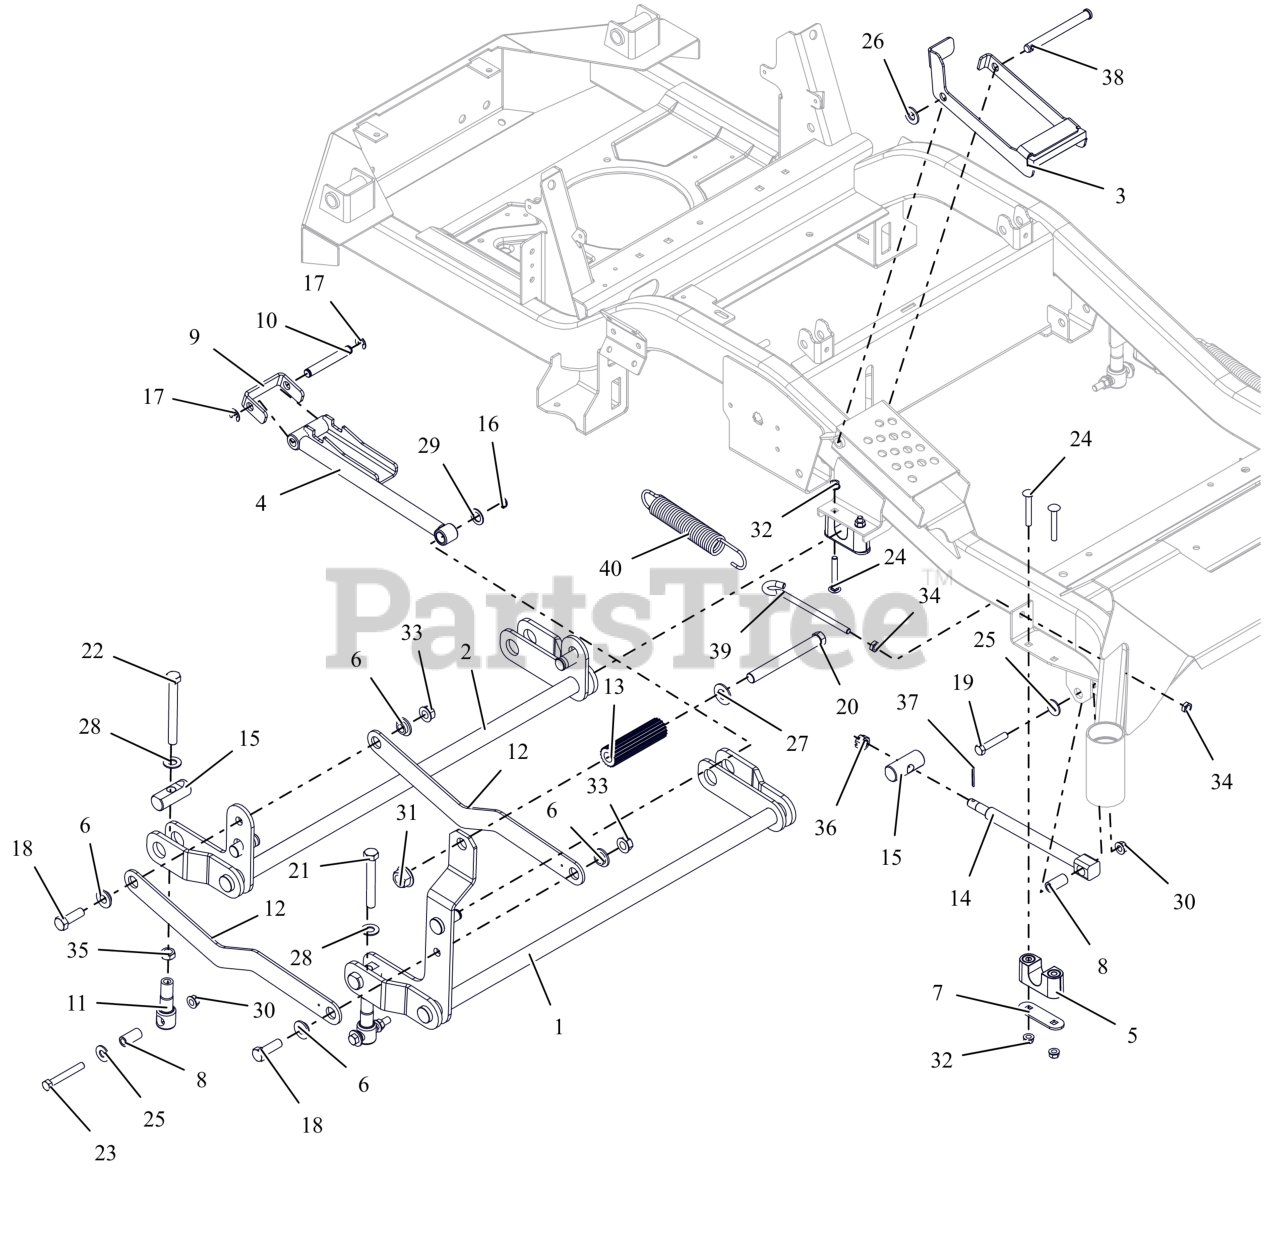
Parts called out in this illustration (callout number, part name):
1	WLDMT, FRONT DECK LIFT PIVOT
2	WLDMT, REAR DECK LIFT PIVOT
3	BRKT, HOC TRANSFER LOCK
4	WLDMT, HOC ARM
5	ASM-BUSHING, DECK LIFT
6	BSHG-FLG .515X.750X.395X1.120
7	PLATE, BEARING SUPPORT
8	SPACER, DECK LEVELING
9	BRKT, HOC LINE
10	ROD, HOC PIVOT
11	LINK, DECK LIFT FORMED
12	LINK, DECK LIFT
13	ROD, FOOT PEDAL (BLACK)
14	DRAG,LINK-HD
15	PIN, DECK LIFT
16	RG-RTNG-EXT .625X.050
17	RG-RTNG-EXT .500X.042 (E)
18	BLT,HEX .50-13X1.50 G5 ZCC
19	BLT,HEX .38-16X2.00 G5 ZCC
20	BLT, HEX .62-11X5.50 G5 FBP
21	BLT, HEX .50-13X3.50F G5 ZCC
22	BLT, HEX .50-13X4.50F G8 ZCC
23	BLT, HEX .38-16X2.75 G8 ZCC
24	BLT, RHSSN.31-18X2.25 G5 ZCC
25	WSHR,FLT .438X1.00X.083 ZCC
26	WSHR,FLT .531X1.062X.095 ZCC
27	WSHRFLT 5/8SAE CARBHARD FBP
28	WSHR, FLT .557X1.040X.102 ZCC
29	WSHR, FLT .630X1.005X.062 ZCC
30	NUT-LK-TOP-FLG .38-16 ZC120
31	NUT,FLG-TOP LK .625-11 FBP
32	NUT,LK-CTR-FLG .31-18 GF ZCC
33	NUT-LK-TOP-FLG .500-13 GF ZCC
34	NUT-JAM .375-16 G2 ZCC
35	NUT-JAM .500-13 G2 ZCC
36	NUT-SL .50-13
37	PIN,CTR.12X1.25EXTPRSQCT ZC120
38	PIN-SLIC .50X4.97X4.55 -ZCC
39	BOLT,.38-16 X 5.25-.62 DIA EYE
40	SG-TENS .162X1.25X8.25 WLD 25
